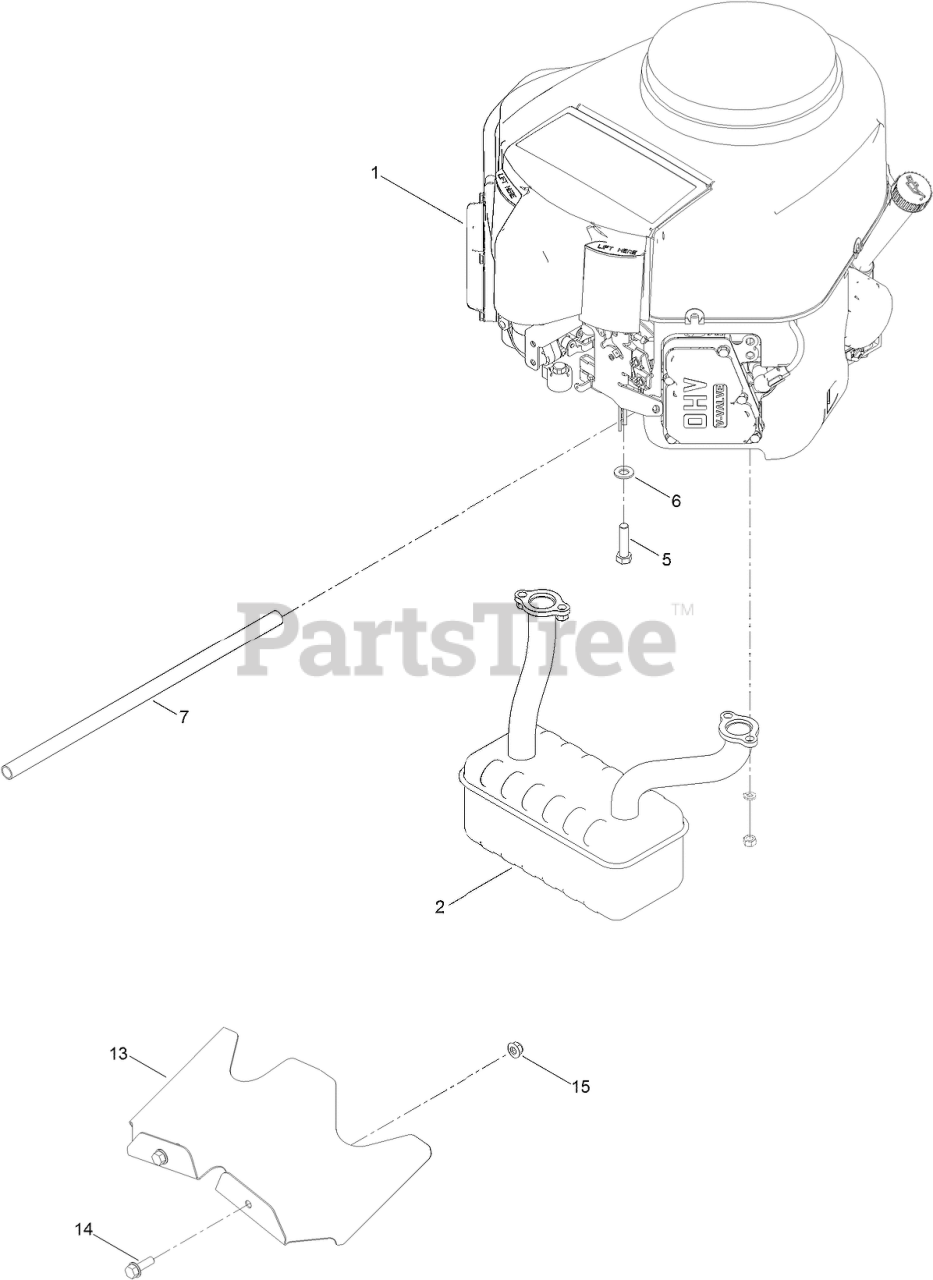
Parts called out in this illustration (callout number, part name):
2	MUFFLER
5	BOLT-HH
6	WASHER-FLAT
7	TUBE-DRAIN, OIL
13	SHIELD-HEAT
14	SCREW-HHF
15	NUT-HF, NI
